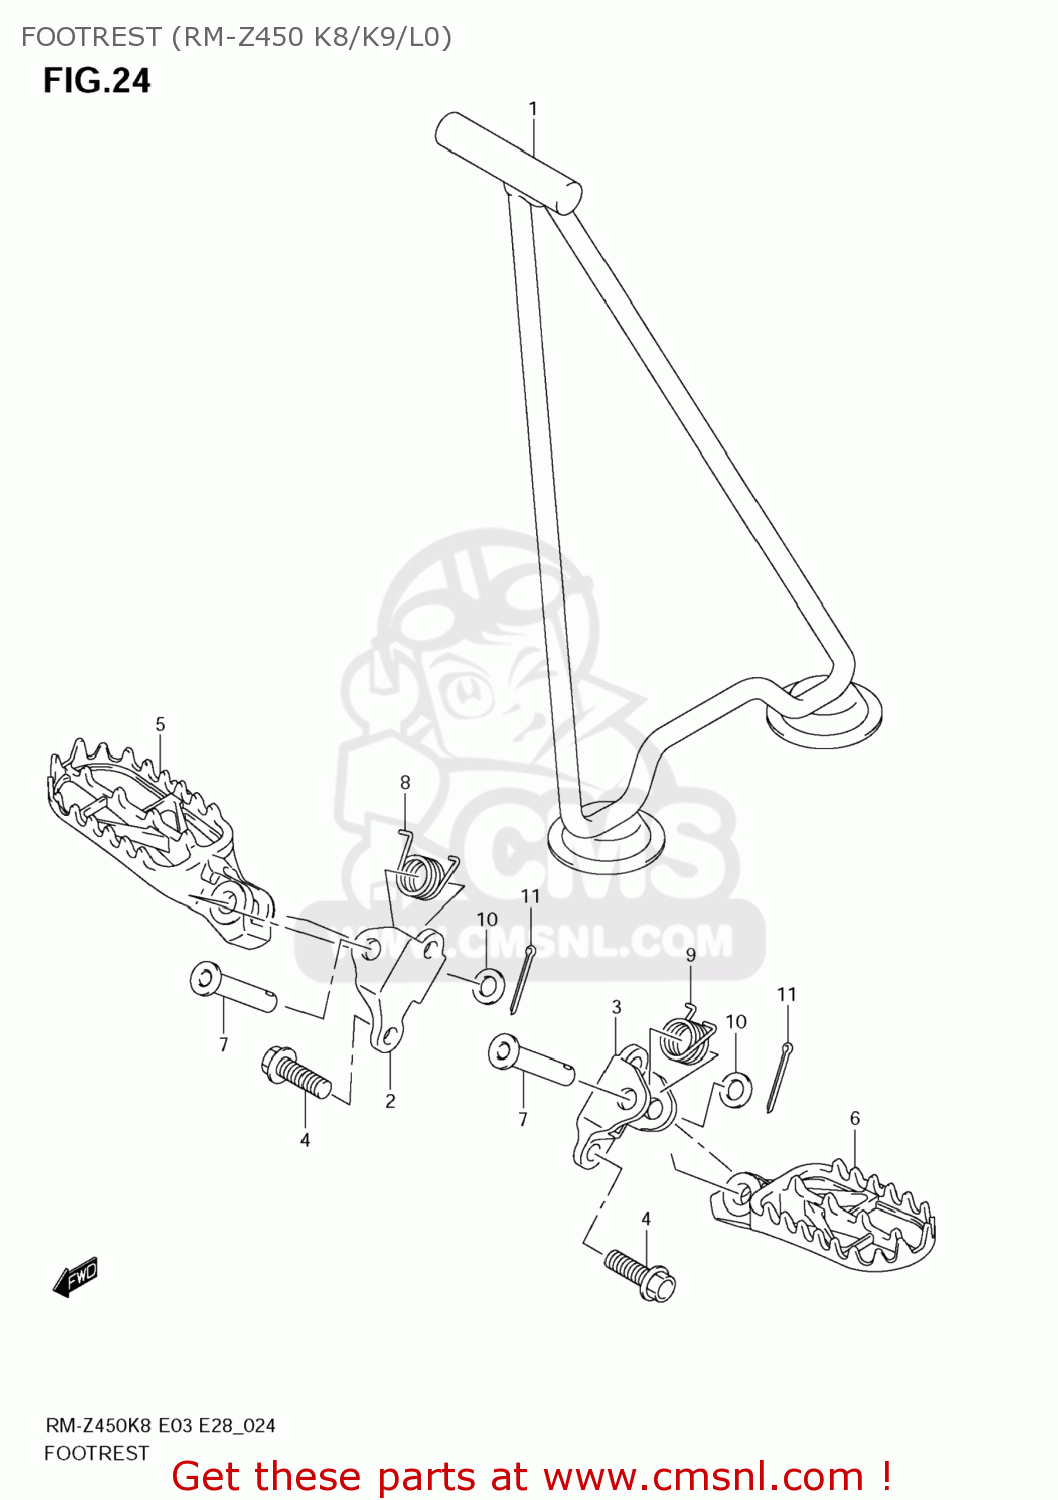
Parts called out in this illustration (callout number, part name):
1	STAND
2	BRACKET,FOOTREST,R
3	BRACKET,FOOTREST,L
4	BOLT(10X25)
5	FOOTREST,R
6	FOOTREST,L
7	PIN(10X41.5)
8	SPRING
9	SPRING
10	WASHER(10.5X18X1)
11	PIN
